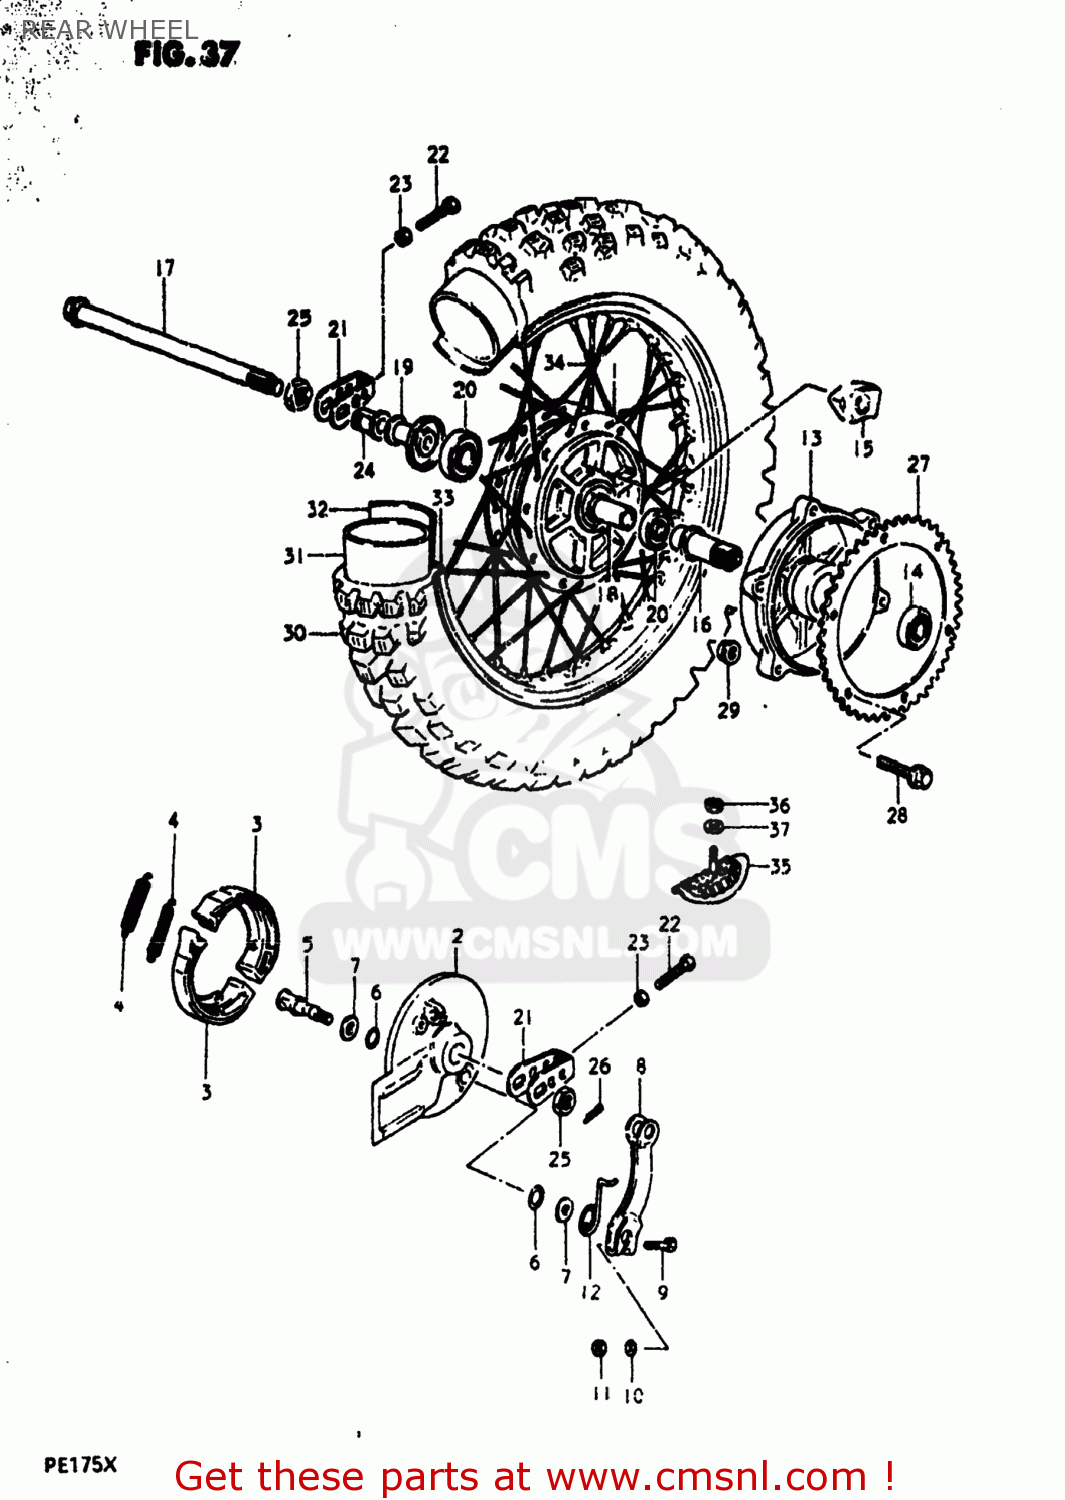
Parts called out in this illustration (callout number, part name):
1	HUB,REAR
2	PANEL,REAR HUB
3	SHOE,BRAKE
4	SPRING(L:34)
5	CAM,REAR BRAKE
6	O-RING (D:2.4 ID:13.8)
7	WASHER (14.5X22X1.6)
8	LEVER,REAR BRAKE CAM
9	BOLT
10	WASHER
11	NUT
12	SPRING
13	DRUM ASSEMBLY,REAR BRAKE
14	BALL BEARING 22X50X14
15	ABSORBER,RR HUB SHOCK
16	SHAFT,REAR BRAKE DRUM
17	AXLE,REAR
18	SPACER,REAR HUB BEARING
19	SPACER,REAR AXLE,RIGHT
20	BEARING
21	ADJUSTER,CHAIN
22	BOLT
23	NUT
24	SPACER,CHAIN ADJUSTER
25	NUT
26	PIN 30X20
27	SPROCKET,REAR (NT:48)(AL)
28	BOLT(8X30)
29	NUT
30	TIRE
31	TUBE ASSEMBLY,WHEEL,INNER
32	PROTECTOR,INNER TUBE
33	RIM,REAR WHEEL
34	SPOKE SET,REAR
35	STOPPER,BEAD
36	NUT
37	WASHER
